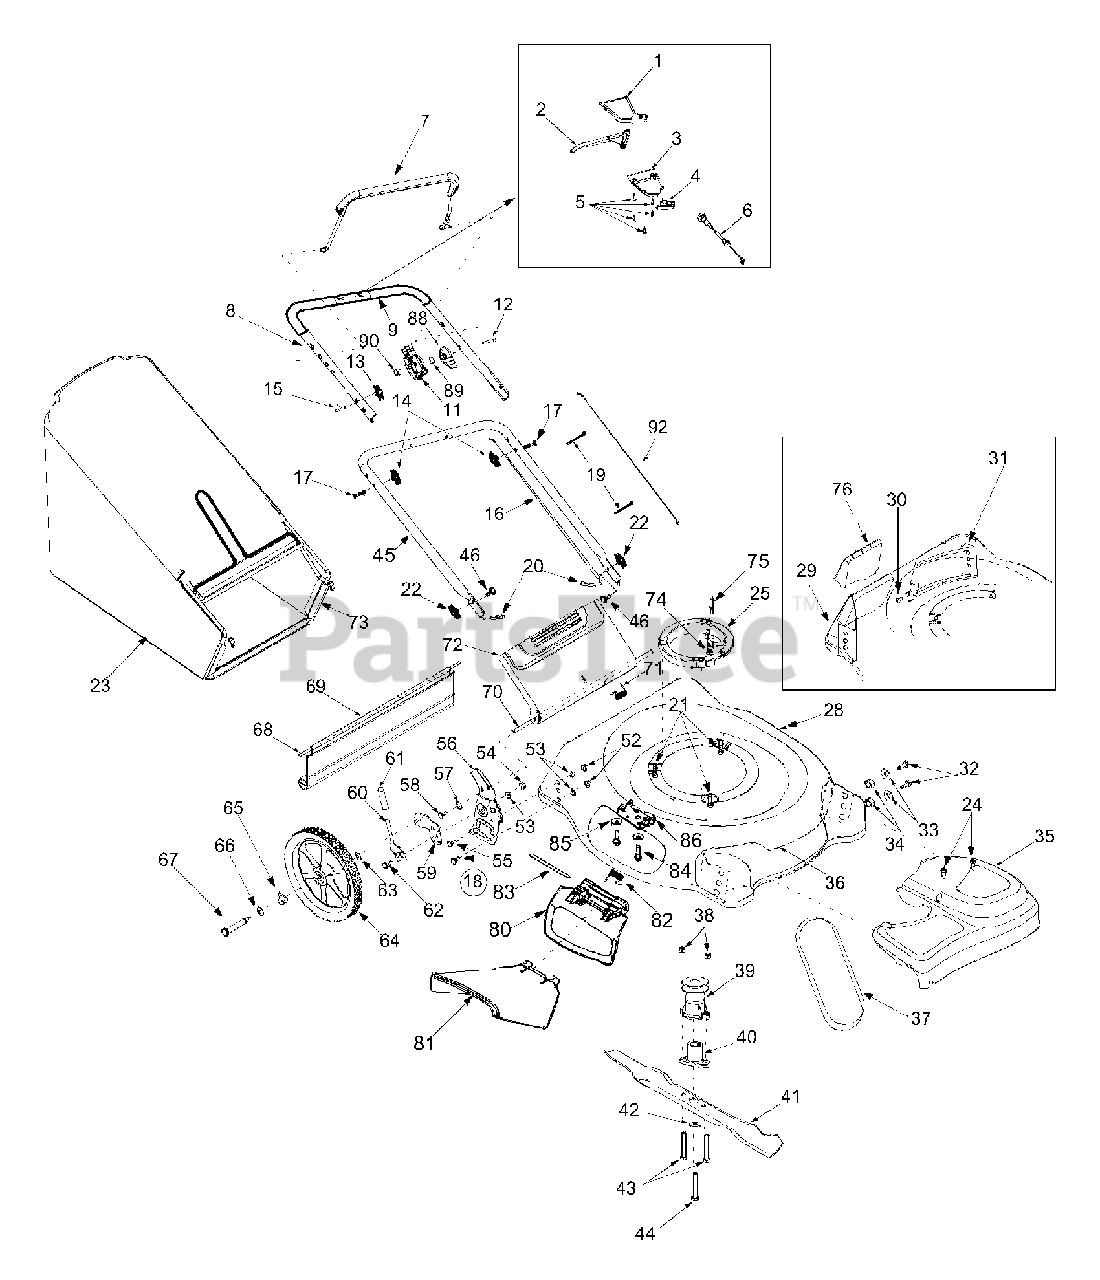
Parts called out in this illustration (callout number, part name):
1	Upper Drive Cover
2	Drive Lever
3	Lower Drive Cover
4	Mounting Cap
5	Screw # 10-16 x .75
6	Drive Cable
9	Foam Grip, 9"
11	Throttle Housing w/Choke
12	Oval C-Sunk Screw 1/4-20 x 1.825
13	Handle Knob
14	Handle Knob
15	Eye Bolt
16	Control Cable, 39"
17	Carriage Bolt 5/16-18 x 2.0
18	RH Bracket Ass'y
19	Cable Tie
20	Cotter Pin
21	Self-Tapping Screw
22	Wing Knob
23	Grass Bag
24	Screw # 12 x .457
25	Engine Spacer
30	Screw AB: 1/4-14: .625
32	Hex Screw 3/8-16 x .75
33	Bell Washer .39 x 1.13 x .062
34	Hex Nut 3/8-16
35	Transmission Cover
38	Hex Nut 1/4-20
39	Drive Pulley
40	Blade Adapter
41	21" Mulching Blade
42	Flat Washer .516 x 1.5 x .134
43	Hex Screw 1/4-20 x 1.50
44	Hex Screw 3/8-24 x 2.50
46	Carriage Bolt, 1/4-20 x .75"
52	Hex Nut 3/8-16
53	Bell Washer .39 I.D. x 1.38 O.D.
54	Hex Flange Lock Nut 3/8-16
55	Hex Scr. w/Washer 1/4-14 x .625
57	Bell Washer .265 x .75 x .062
58	Hex Screw TT 1/4-20 x .500
59	RH Pivot Bar
60	Height Adj. Lever
61	Foam Grip
62	Shoulder Scr .500 Dia. x .434
63	Washer .401 x .870 x .063
64	Wheel, 14 x 2
65	Spring Washer .50 I.D. x 1.0 O.D.
66	Flat Washer .510 x 1.373 x .04
67	Shoulder Screw
68	Wire
69	Rear Trailing Shield
70	Pivot Rod
71	Torsion Spring
74	Hex Nut
75	Screw
80	Mulching Plug (Hinged)
81	Chute Deflector
82	Torsion Spring
83	Hinge Pin
84	Tapp Scr. 1/4-20 x .500
85	Bell Washer .265 x .75 x .062
88	Throttle Lever
89	Curved Spring Washer
90	Hex Lock Nut 1/4-20
92	Throttle Cable
